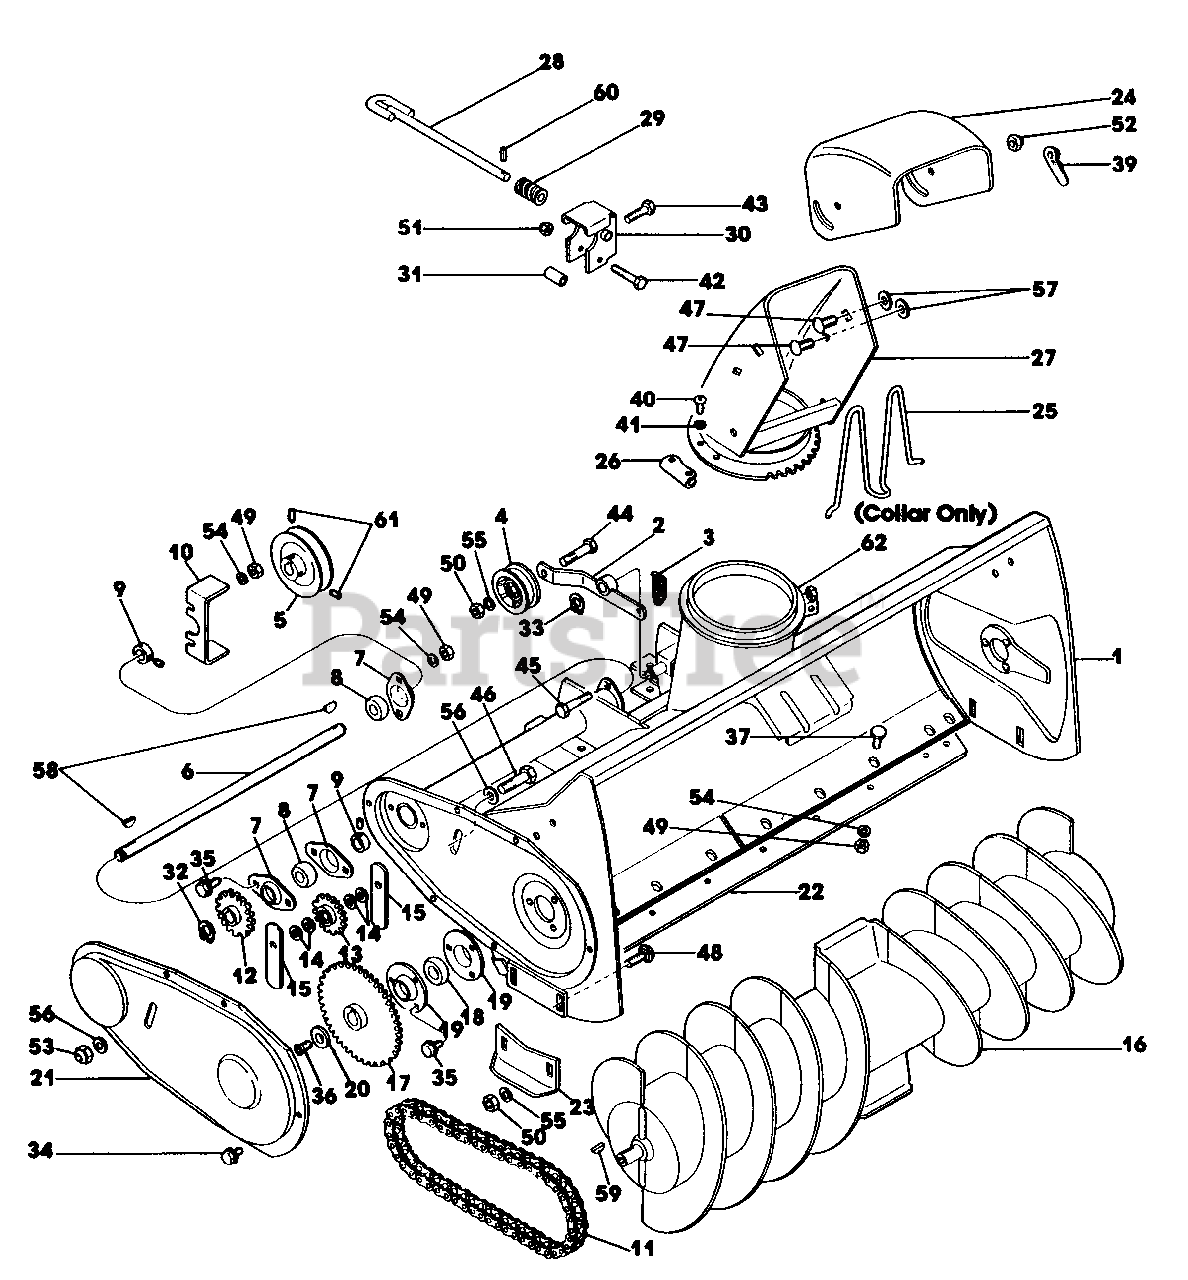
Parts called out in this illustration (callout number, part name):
1	Collector Housing Assembly w/Decals
2	Idler Arm Assembly
3	Spring Idler
4	Idler Pulley
5	Pulley
6	Output Shaft
7	Flangette Stamping
8	Bearing
9	Collar w/Setscrew
10	Belt Retainer
11	Chain
12	Sprocket Assembly
13	Idler Sprocket
14	Spacer
15	Strip
16	Collector Assembly
17	Sprocket Assembly
18	Bearing
19	Flangette
20	Washer
21	Drive Cover
22	Scraper Blade
23	Skid
24	Deflector & Decal Assembly
25	Discharge Guard
26	Retainer
27	Discharge Guide Assembly
28	Worm Shaft Assembly
29	Worm Gear
30	Worm Support
31	Spacer-Worm Support
32	Snap Ring
33	Snap Ring
34	Lock Screw 5/16-18 x 1/2
35	Lock Screw 5/16-18 x 1/2
36	Machine Screw, Hex Socket Flat Hd. 5/16-18 x 3/4
37	Wafer Hd. Bolt 5/16-18 x 3/4
39	Wing Nut
40	Self Tapping Screw #6-32 x 3/8
41	Lock Washer #6
42	Cap Screw, Hex Hd. 5/16-20 x 2 Plated, Grade 5
43	Cap Screw, Hex Hd. 5/16-18 x 1-1/2 Plated, Grade 5
44	Cap Screw, Hex Hd. 3/8-16 x 2 Plated, Grade 5
45	Cap Screw, Hex Hd. 5/16-18 x 1-1/8 Plated, Grade 5
46	Cap Screw, Hex Hd. 1/2-13 x 2 Plated, Grade 5
47	Bolt Carriage 3/8-16 x 3/4 Plated
48	Bolt, Carriage 3/8-16 x 1 Plated
49	Nut, Hex 5/16-18 Plated
50	Nut, Hex 3/8-16 Plated
51	Nut, Hex Cone Lock 1/4-20 Plated
52	Nut, Hex Cone Lock 3/8-16 Plated
53	Nut, Hex Cone Lock 1/2-13 Plated
54	Washer, Spring Lock 5/16 Plated
55	Washer, Spring Lock 3/8 Plated
56	Washer, Flat SAE 1/2 Plated
57	Washer, Flat 1/2 Plated
58	Key, Woodruff 3/16 x 3/4
59	Key, Woodruff 1/4 x 3/4
60	Pin, Roll 1/8 x 3/4 Plated
61	Set Screw, Hex Socket Hd. Cup Pt. 5/16-18 x 5/16 Plated
62	Chute Collar
